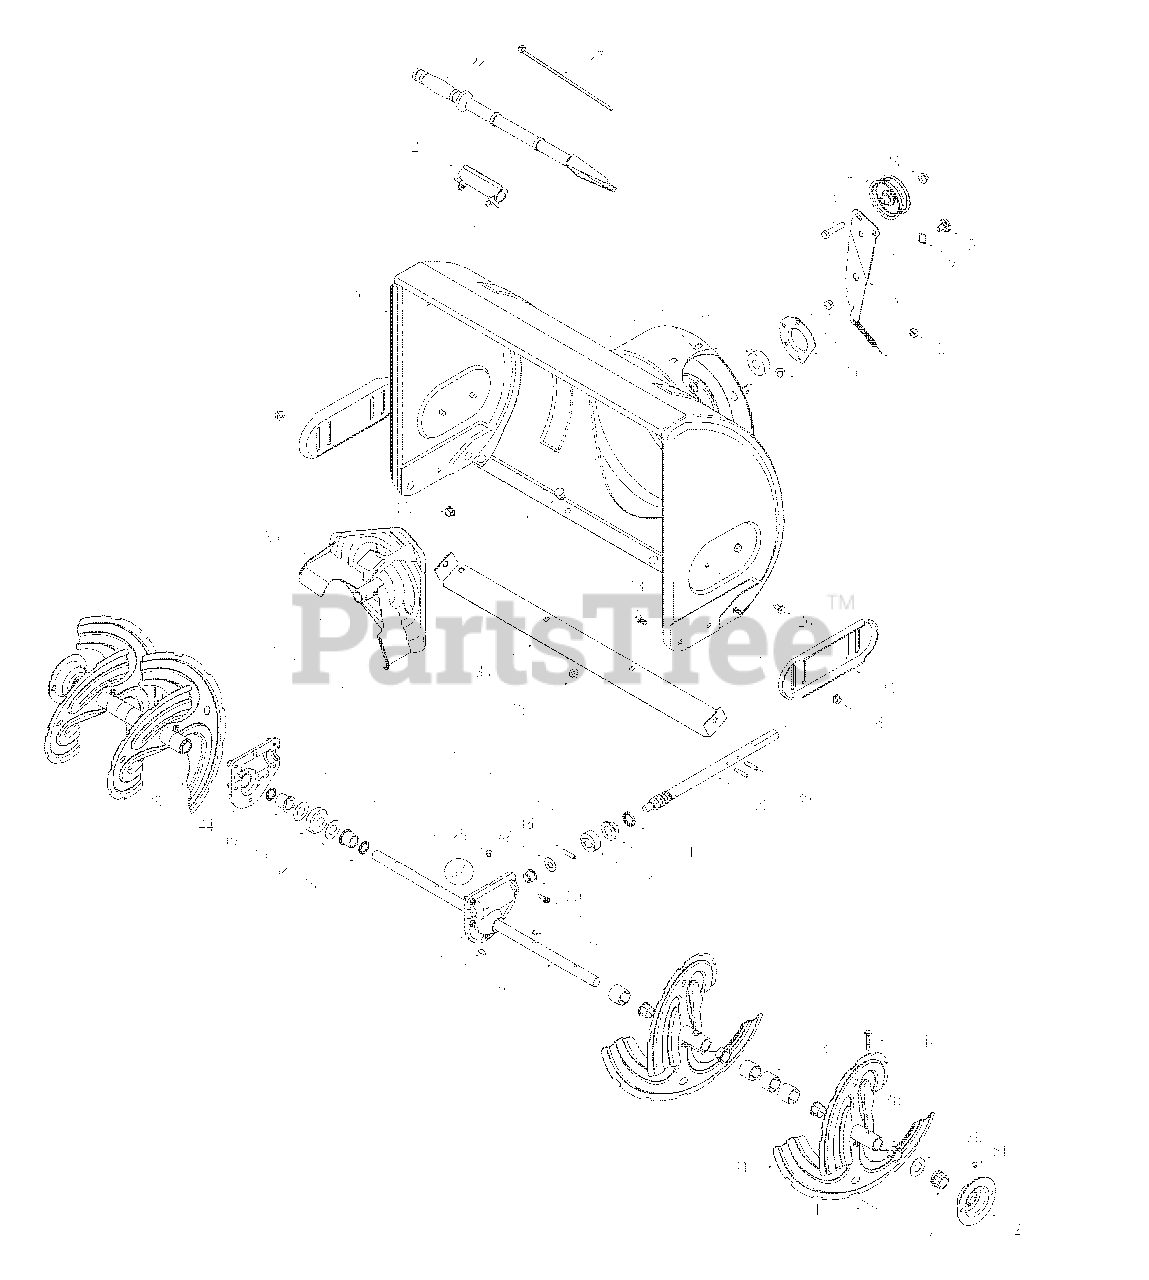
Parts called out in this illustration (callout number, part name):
1	Cotter Pin
2	Flat Idler
4	Hex Cap Screw 3/8-16 x 1.75
5	Shoulder Screw
6	Wave Washer
7	Extension Spring
8	Hex Nut 5/16-18
9	Self Tapping Screw, 1/4-20 x.75
10	Auger Axle, 28"
12	Ball Bearing
13	Carriage Bolt, 5/16-18 x.75
17	Hi-Pro Key, 3/16 x 5/8
19	Worm Gear, 20-tooth
20	Worm Shaft
21	Clean-Out Tool Mount
22	Clean-Out Tool
23	Thrust Collar
25	Grease Plug
26	Hex Screw 5/16-12
27	Cable Tie
28	Flange Lock Nut 3/8-16
29	Hex Flange Bearing
31	Grease Seal
32	Flat Washer,.76 x 1.5 x.030
34	Carriage Bolt 5/16-18 x 1.00
37	Gear Assembly Complete, 28"
39	Flat Washer
40	Flange Bushing
42	Shear Pin,.25 x 1.50
43	Spacer, 1.25OD x.75ID x 1.00 Lg.
44	RH Housing
46	Flange Bearing
47	LH Housing
48	Flat Washer,.51 x 1.12 x.06
49	Flange Bearing,.75 x 1.0 x.59
50	Flange Bearing,.503 ID x.75 OD
51	Lube Fitting, 3/16 Drive
